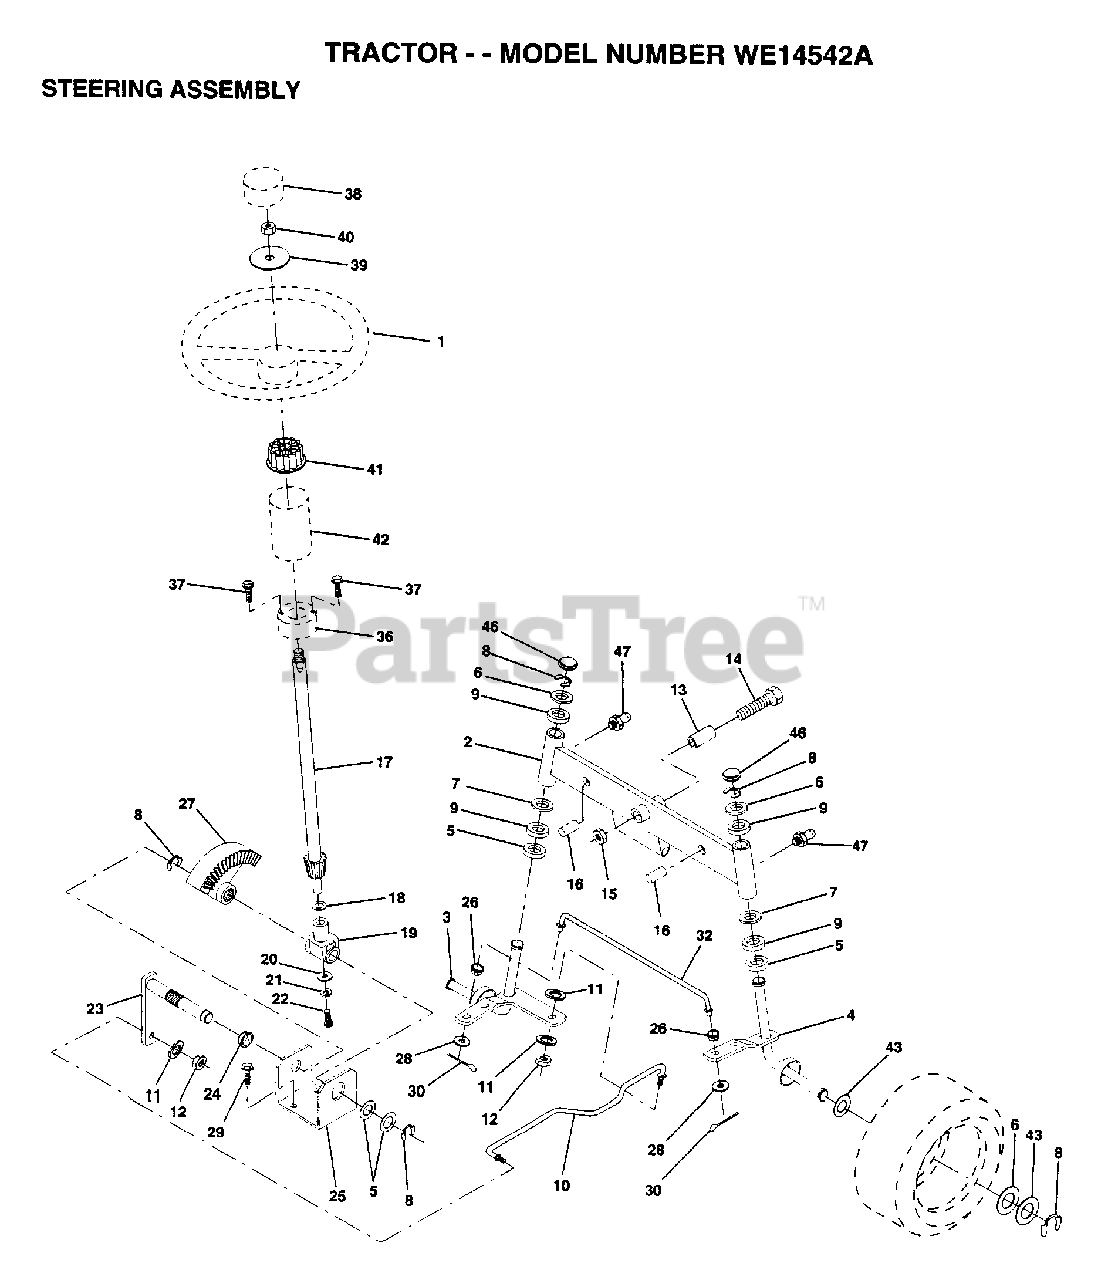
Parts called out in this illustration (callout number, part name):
2	AXLE ASM FRONT
3	SPINDLE LH
4	SPINDLE RH
5	WASHER .T
6	WASHER
7	WASHER
8	RING
9	COL. SRTG. BEAR.
11	LOCKWASHER
13	BEARING
14	BOLT HEX 5/8-11
15	"NUT-LOC,FLANGE LT"
16	AXLE PIN
17	SHAFT ASM
18	THRUST WASHER
19	SUPPORT.SHAFT
21	LOCKWASHER
22	"SCREW,SPECIAL"
24	NYLINER T
25	"BRKT,STEERING"
26	BUSHING.DRAGLINK
27	GEAR SECTOR
28	WASHER
29	SCREW
30	COTTER PIN
32	TIE ROD
38	ST WHL INSERT CAP
39	WASHER T
40	GRIPCO NUT
41	ADAPTER-WHEEL LT
42	"TUBE, STR SHAFT"
43	WASHER
46	CAP
47	ZERK M
